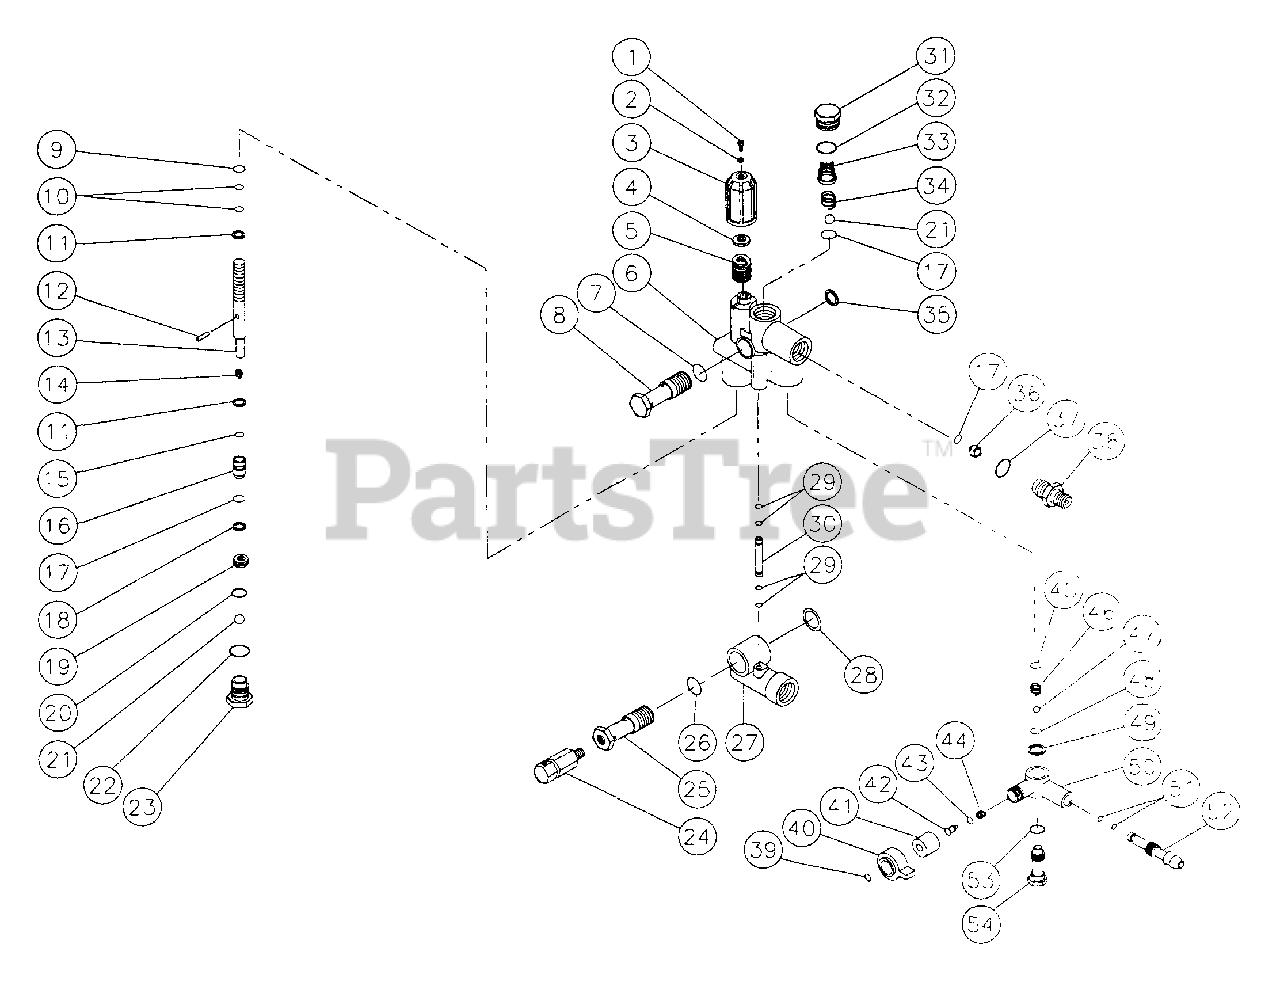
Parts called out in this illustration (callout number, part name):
3	Pressure Regulating Knob
4	Spring Guide
6	Valve Body - Brass
8	Fixing Screw
9	Back-up Ring
13	Piston Guide
16	Drive Piston
18	Back-up Ring
19	Valve Seat
24	Thermo Valve
25	Fixing Screw
27	Inlet Body
30	By-pass Tube
33	Valve Guide
36	Orifice
39	Snap Ring
40	Injector Regulating Knob
41	Knob Insert
50	Injector Body
52	Hose Barb
54	Valve Seat
